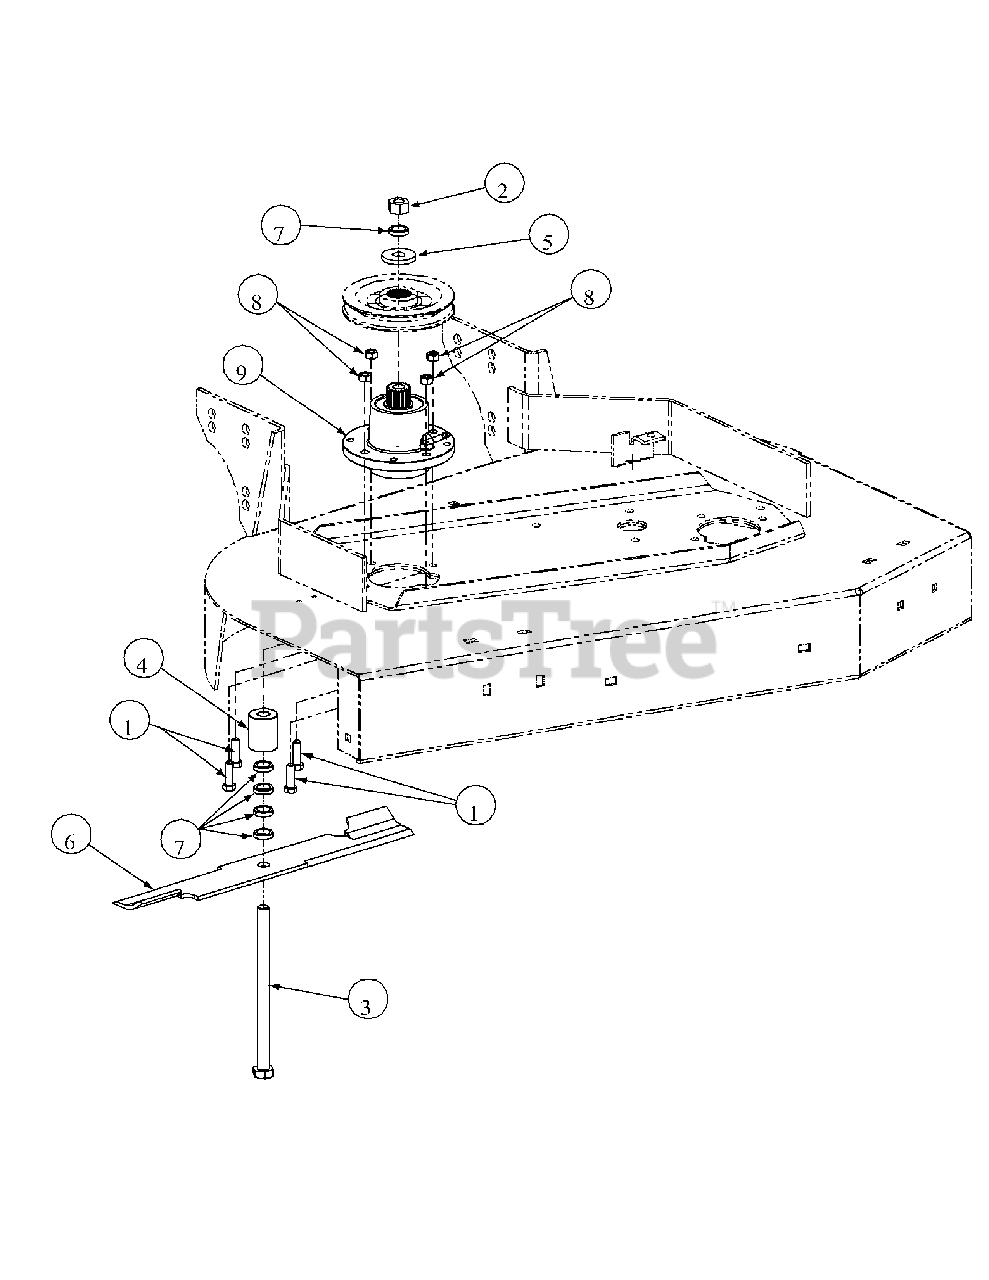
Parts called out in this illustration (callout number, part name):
1	Hex Cap Screw, 3/8-16 x 1-1/4
2	Hex Nut, 5/8-11
3	Hex Cap Screw, 5/8-11 x 9
4	Blade Spacer, .630 x 1.500 x 1.850
5	Flat Washer, .656 ID x 1.313 OD
6	18" Rotary Blade (36" Deck)
7	Blade Spacer, 5/8 ID, 1/4 Thick
8	Lock Nut, 3/8-16
9	Spindle Assembly
